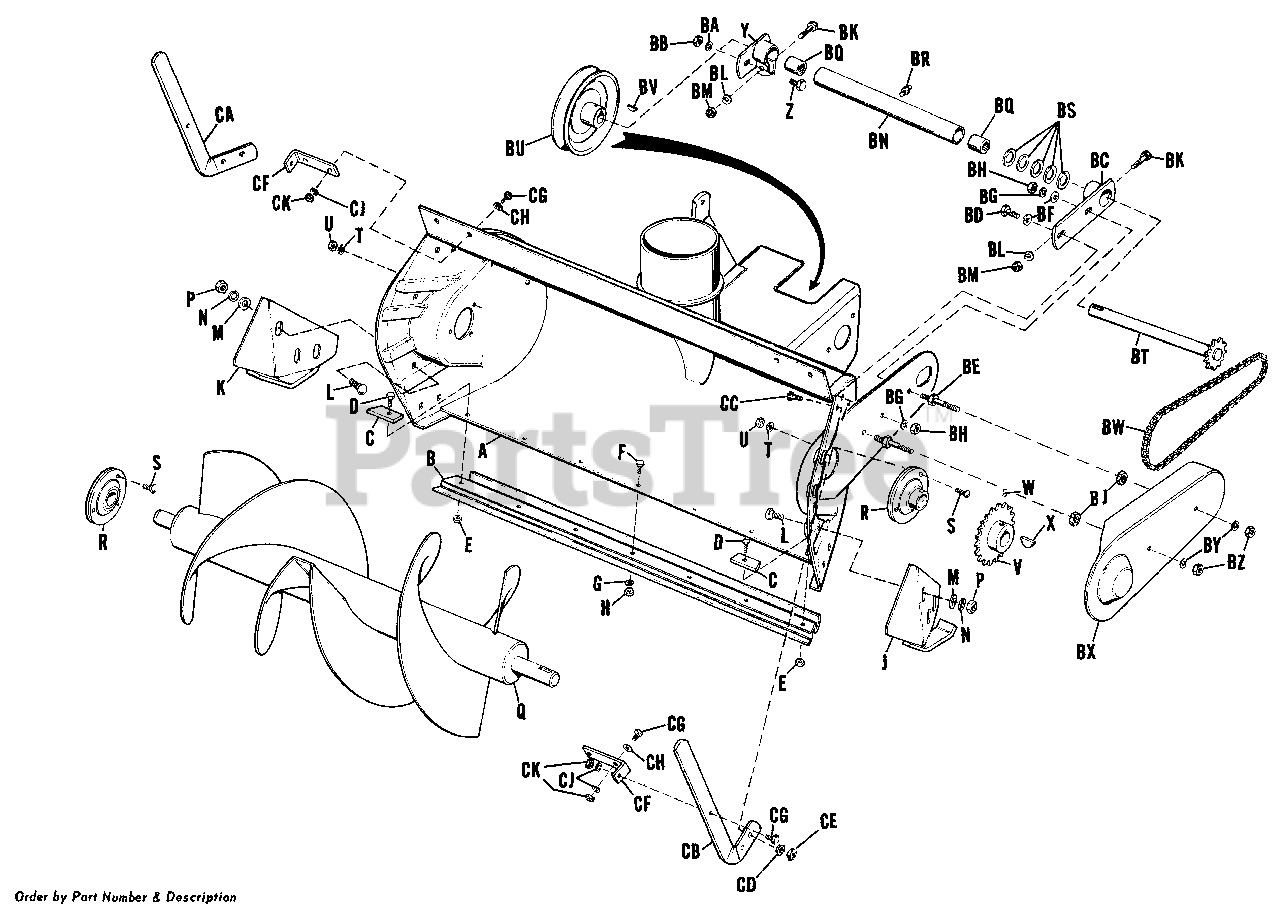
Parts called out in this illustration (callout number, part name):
A	Body Assembly
B	Body Scraper
C	Scraper Clamp
D	Hex Capscrew, 5/16"-18 x 7/8" lg.
E	Hex Lock Nut, Full, 5/16"-18
F	Hex Capscrew, 1/4"-20 x 5/8" lg.
G	Lock Washer, 1/4"
H	Hex Nut, Full, 1/4"-20
J	Shoe Assembly, Left Hand
K	Shoe Assembly, Right Hand
L	Carriage Bolt, 3/8"-16 x 3/4" lg.
M	Plain Washer, 3/8"
N	Lock Washer, 3/8"
P	Hex Nut, Full, 3/8"-16
Q	Rotor Assembly
R	Ball Bearing
S	Hex Capscrew, 5/16"-18 x 3/4" lg.
T	Lock Washer, 5/16"
U	Hex Nut, Full, 5/16"-18
V	Rotor Sprocket
W	Set Screw, Socket Hd., Cup Pt., 5/16"-18 x 5/16" lg.
Y	Clamp Support Assembly
Z	Hex Capscrew, 3/8"-16 x 1" lg.
BA	Lock Washer, 3/8"
BB	Hex Nut, Full, 3/8"-16
BC	Clamp Support Assembly
BD	Hex Capscrew, 3/8"-16 x 1" lg.
BF	Plain Washer, 3/8"
BG	Lock Washer, 3/8"
BH	Hex Nut, Full, 3/8"-16
BJ	Hex Lock Nut, Full, 3/8"-16
BK	Hex Capscrew, 5/16"-18 x 1-1/2" lg.
BL	Lock Washer, 5/16"
BM	Hex Nut, Full, 5/16"-18
BN	Bearing Housing
BQ	Needle Bearing
BR	Grease Fitting, #1641 Alemite
BT	Shaft Assembly
BV	Woodruff Key
BW	Chain, w/Conn. Link
BX	Chain Guard
BY	Lock Washer, 3/8"
BZ	Hex Nut, Full, 3/8"-16
CA	Drift Cutter, Right Hand
CB	Drift Cutter, Left Hand
CC	Hex Capscrew, 3/8"-16 x 3/4" lg.
CD	Lock Washer, 3/8"
CE	Hex Nut, Full, 3/8"-16
CG	Hex Capscrew, 5/16"-18 x 3/4" lg.
CH	Plain Washer, 5/16"
CJ	Lock Washer, 5/16"
CK	Hex Nut, Full, 5/16"-18
